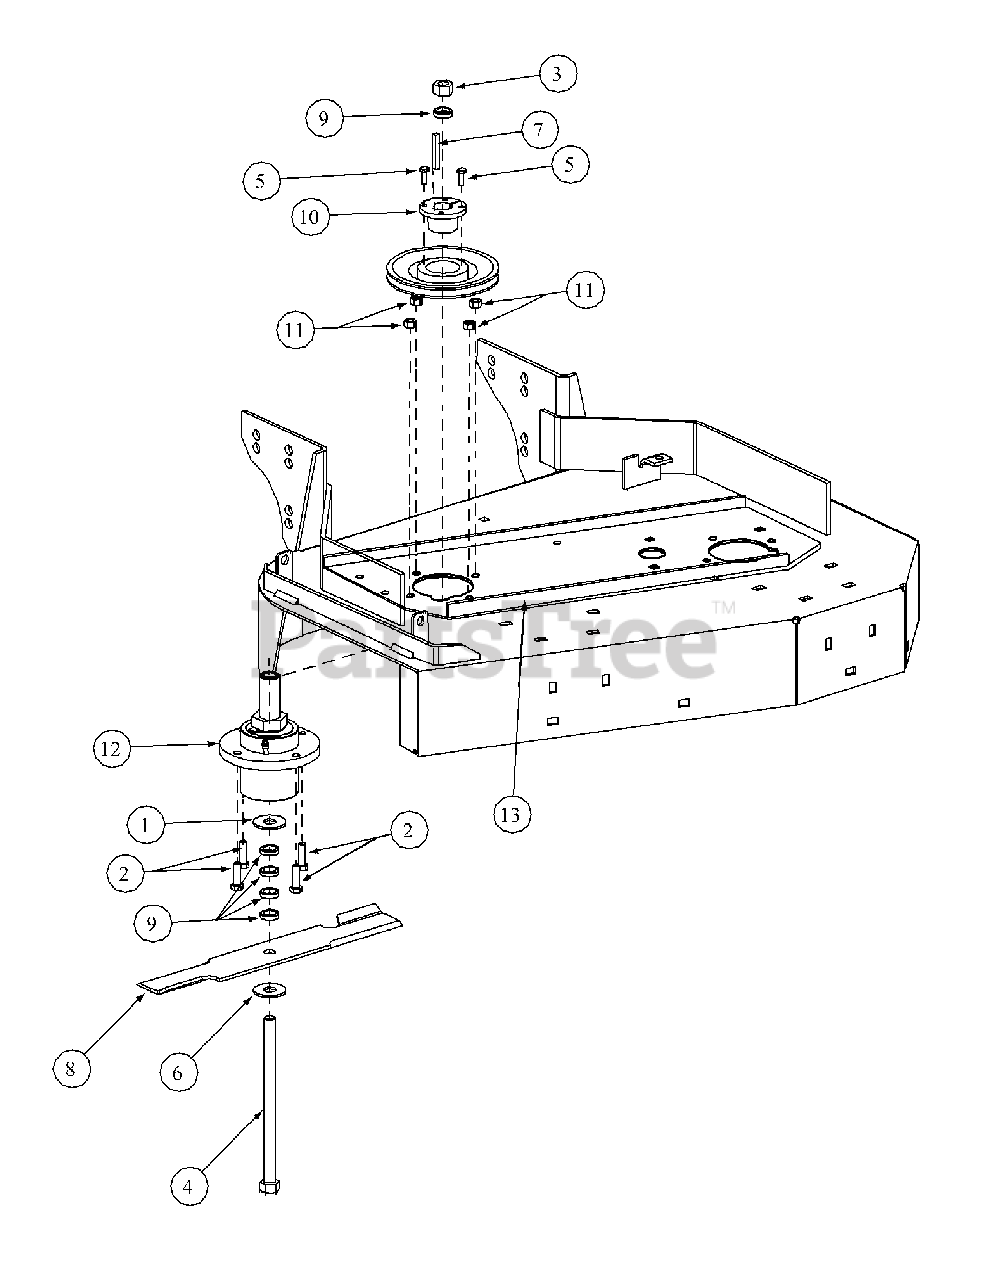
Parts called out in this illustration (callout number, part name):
1	Flat Washer, 1-1/2 x 5/8 x .05
2	Hex Cap Screw, 3/8-16 x 1-1/4
3	Hex Nut, 5/8-11
4	Hex Cap Screw, 5/8-11 x 9-1/2
5	Hex Cap Screw, 1/4-20, .75
6	Flat Washer, 5/8 Zinc
7	Key Stick, 1/4 x 1/4 x 2
8	Rotary Blade, 16-1/2
9	Blade Spacer, 5/8 ID, 1/4 Thick
10	Bushing
11	Lock Nut, 3/8-16
12	Spindle Assembly
13	Deck Stiffener
